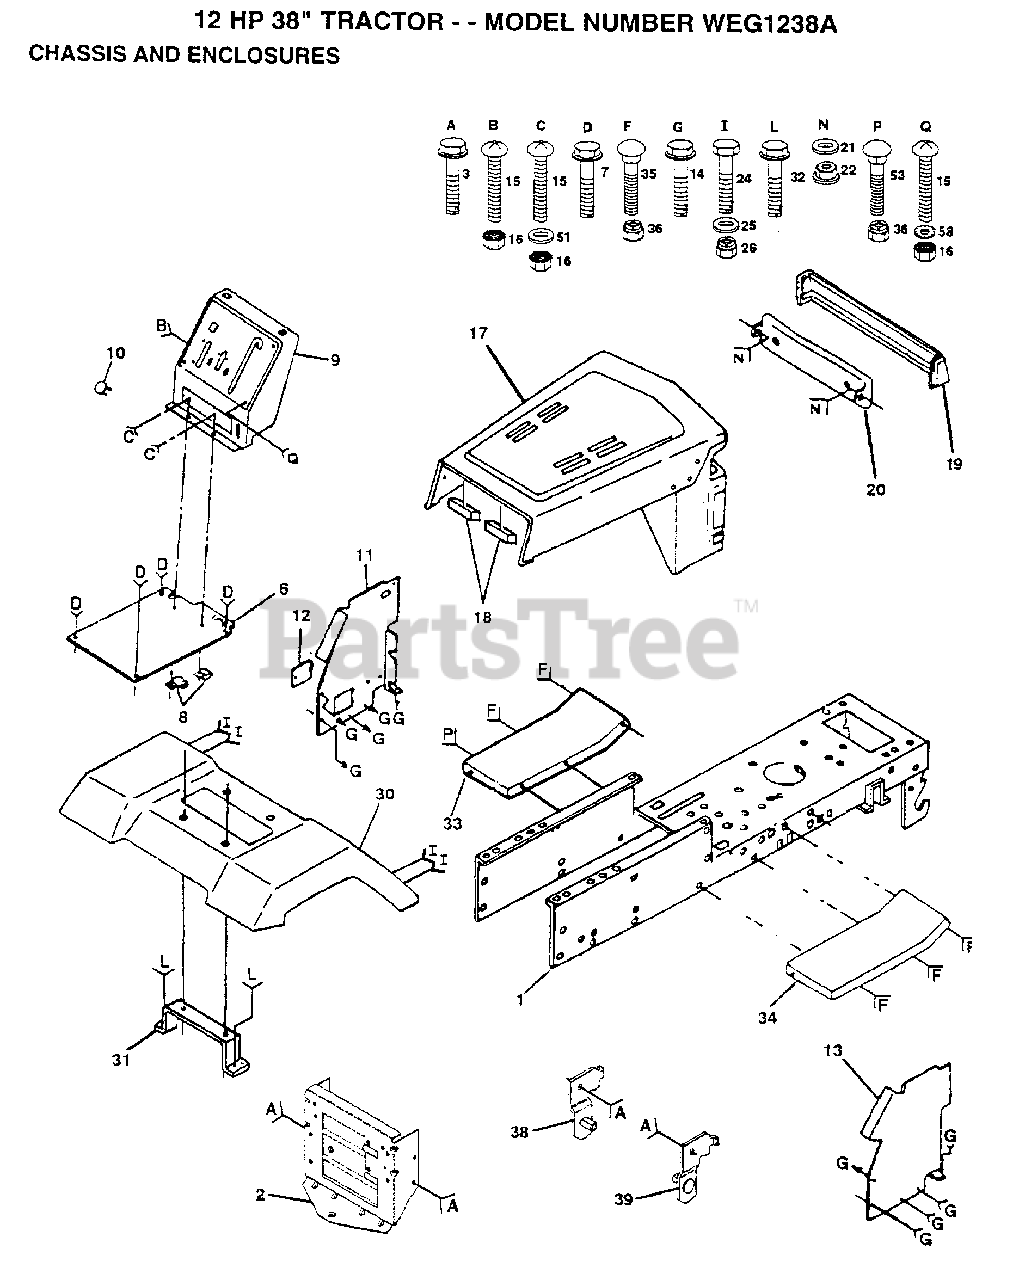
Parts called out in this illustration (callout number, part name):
3	SCREW
7	SCREW
8	CLIP T
9	DASH SILKSCRN 1
10	PLUG BUTTON T
11	PANEL DASH LH
12	COVER ACCESS
14	SCREW LT
15	SCREW
17	HOOD/GRILL ASM
21	WASHER PM
22	PAL NUT LT
24	BOLT
25	WASHER
26	NUT
31	BRKT FENDER
32	SCREW
33	FOOTREST LH
34	FOOTREST
35	BOLT
36	NUT
38	BRACKET ASM LH
39	BRACKET ASM RH
51	WASHER
58	LOCKWASHER
